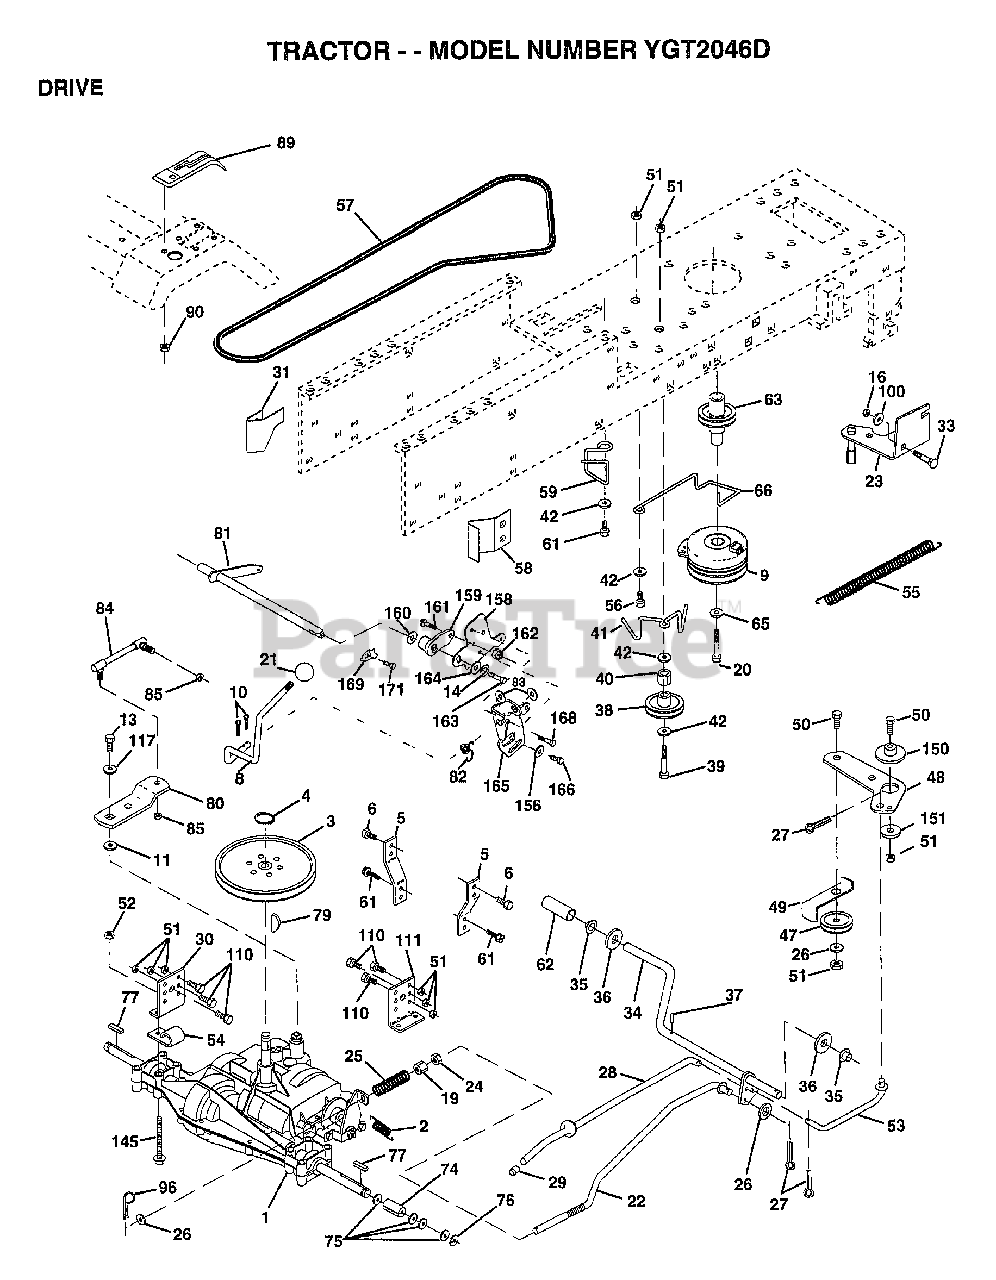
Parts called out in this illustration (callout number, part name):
3	PULLEY TRANSAXLE
4	RING
5	STRAP TORQUE
6	SCREW
8	ROD.SHIFT.FEND.ADJ.YT
9	CLUTCH.ELECTRIC
10	PIN COTTER 1/8
11	WASH-SHFT PLT LT
13	BOLT.1/4-28.W/PAT
14	LOCKWASHER
16	NUT
19	NUT
20	BOLT.7/16-20X4.25
21	KNOB.DUCKHEAD.1/2
22	ROD.ASM.BK.44.MWR
23	BRACKET.CLUT.MTG.
24	NUT
25	"SPRING,ROD BRAKE"
26	WASHER
27	COTTER PIN
28	ROD.BRAKE.PARK.LT
29	PLUNGER CAP T
30	BRKT TRANS LH
31	KEEPER BELT LH
33	BOLT
34	SHAFT ASM-PEDAL F
35	NYLON BEARING
36	WASHER LT
38	FLAT IDLER PULLEY
39	BOLT
40	SPACER T
41	"KEEPER,BELT.IDLER FLAT"
42	WASHER
48	BELLCRANK.CLUTCH
49	RETAIN BELT
53	"LINK, CLUTCH T"
54	"CLIP,INSULATOR"
55	"SPRING, RETURN LT"
57	V-BELT.DRIVE
58	"KEEPER,BELT RH"
59	KEEPER BELT CNTSP
61	SCREW
62	"COVER,PEDAL"
63	PULLEY.CLUTCH.EVX
65	LOCKWASHER
66	KEEPER-BELT
74	SPACER HYT
75	WASHER
76	E RING HYT
77	SQ KEY STD
80	"ARM,SHIFT"
81	SHAFT ASM. CROSS TAPERED
82	"SPRING,TORSION"
83	WASHER
84	LINK TRANSAXLE
85	NUT.CNT.LOCK.1/4
89	CONSOLE.SHIFT.6SP.GTV.BLACK
90	NUT
96	RETAINER M
100	WASHER M
111	BRKT TRANS RH
117	WASHER PM
145	BOLT.HEX.FLGHD
150	BUSHING.BELLCRANK.GRD.DR
151	WASHER
156	WASHER.SRRTD.5/16
158	BRKT.SHIFT.MOUNT
159	HUB.SHIFT
160	WASHER
161	BOLT T
164	WASHER.5/8X.281X10GA
165	BRKT.PIVOT.LEVER
166	SCREW.5/16-18X5/8
168	BOLT.SHOULDER.5/16-18X.561
169	PLATE.FASTENING
171	SCREW LT
